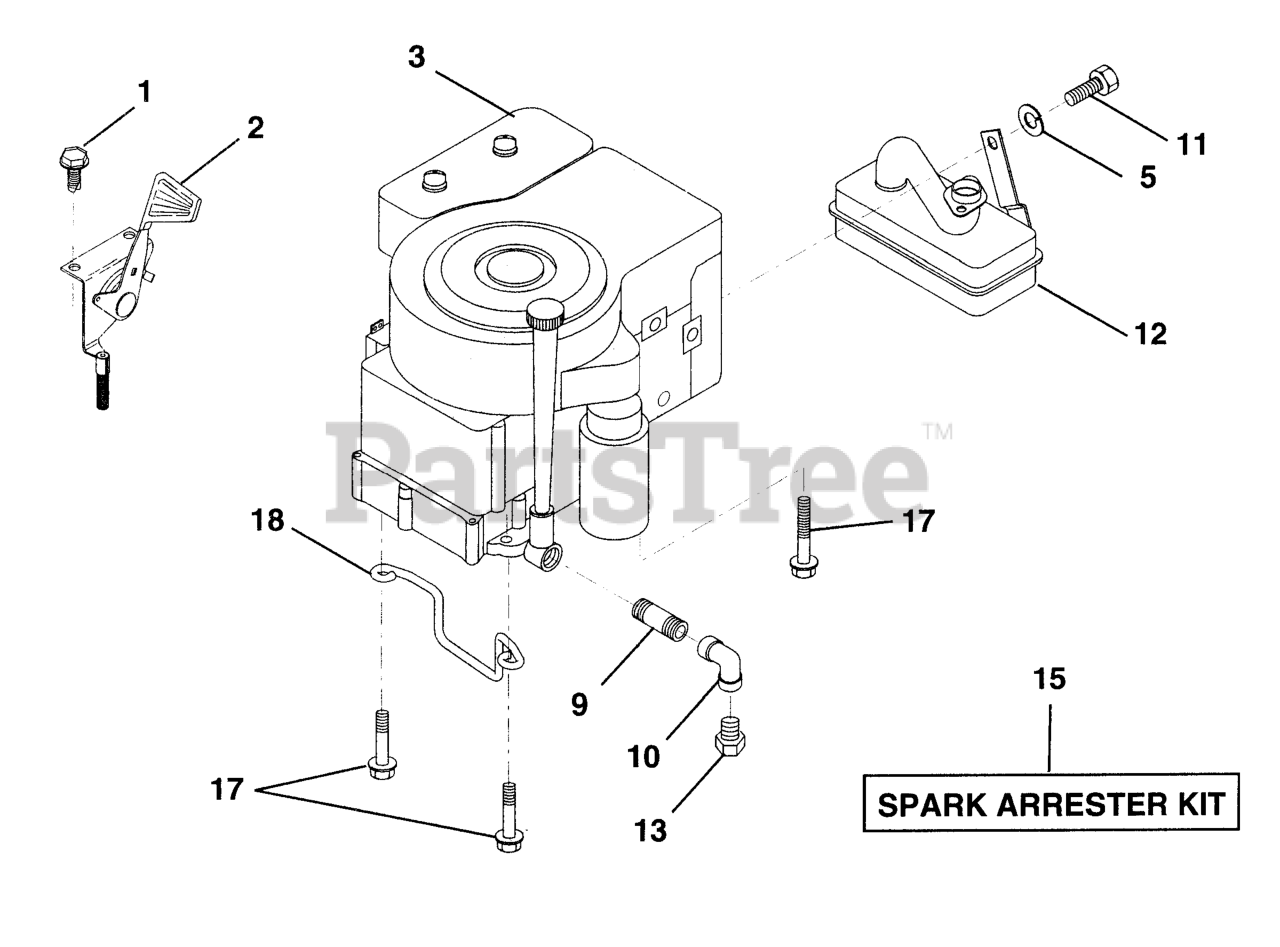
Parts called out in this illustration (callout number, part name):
2	THROTTLE CONTROL
5	WASHER.LOCK.HVY.HLCL.SPR.5/16
9	Nipple, Pipe 3/8 N.P.T. x 3-1/2
10	ELBOW
11	Bolt, Hex Head, Fin. 5/16-18 x 1/2
12	MUFFLER KOH
13	Plug, Oil Drain
15	KIT.SPARK ARRESTOR 794945 B&S
17	BOLT, HEX
18	KEEPER,DR BELT GR
